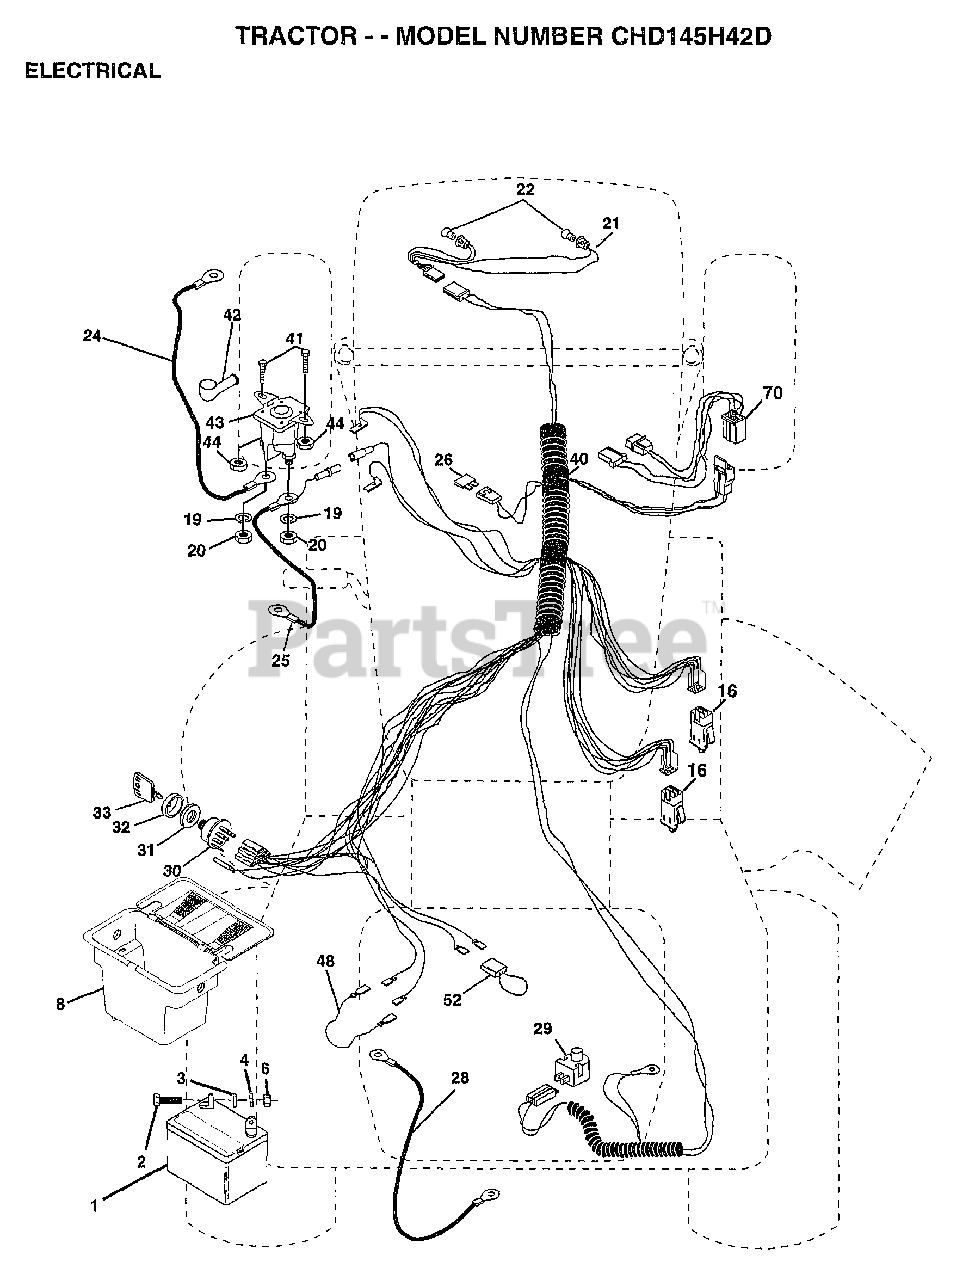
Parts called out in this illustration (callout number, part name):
2	BOLT LT
3	WASHER
4	LOCKWASHER
8	"CASE,BATTERY.MECH"
16	SWITCH INTERLOCK
20	NUT
21	"HARNESS,LIGHT SOC"
22	HEADLAMP BULB
24	"CABLE T, BATTERY"
25	CABLE.BTRY.6GA.RD
26	FUSE HYT
28	CABLE T
29	SWITCH SEAT
30	SWITCH IGN 4POS
31	NUT IGNITION
32	COVER KEY SWITCH
33	KEY
40	HARNESS-IGNITION
41	BOLT HXHD FIN
44	NUT HXKEP 1/4X20
48	ADAPTER AMMETER
52	PROTECTION LOOP
70	HARNESS.ENG.DUAL
